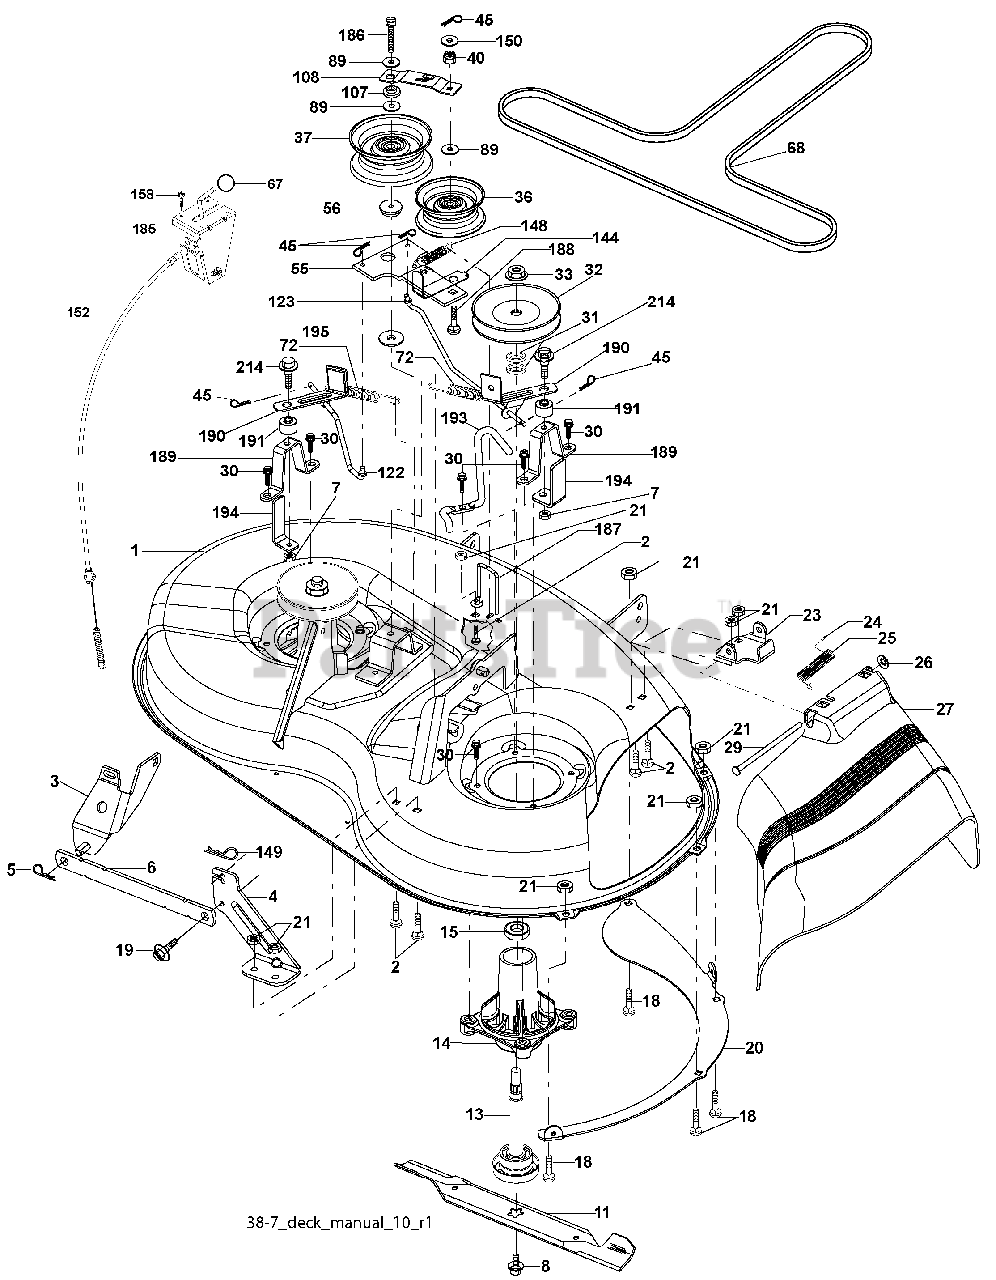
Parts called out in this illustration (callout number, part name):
1	Mower Housing Assembly
2	Bolt Carriage 5/16-18 x 3/4
3	Bracket Asm Fr. Sway Bar
4	Bracket Deck Sway Bar 38"/42"
5	Retainer Spring
6	Bar Sway Deck
7	Nut Lock 5/16-18 unc
8	Bolt 3/8-24 x 1.25 Gr. 8
11	Blade Mower
13	Shaft Assembly, Mandrel, Vented
14	Housing, Mandrel, Vented
15	Bearing, Ball, Mandrel
18	Blade Rdhd Sqnk 5/16-18 x 5/8
19	Bolt, Shoulder
20	Baffle Vortex Front
21	Nut
23	Bracket, Mower Deflector
24	Cap, Sleeve
25	Spring, Torsion, Deflector
26	Nut, Push
27	Shield, Deflector
29	Rod, Hinge
30	Screw Thdrol.
31	Washer, Spacer
32	Pulley, Mandrel
33	Nut, Toplock
36	Pulley, Idler, Flat
37	Pulley, Idler, Flat
40	Nut, Crownlock 3/8-16 unc
45	Retainer
55	Idler Arm Assembly
56	Spacer, Retainer
67	Knob
68	V-Belt
72	Spring Brake Return
89	Washer 13/32 x 13/16 x 11 Ga.
107	Spacer Retainer
108	Stiffener, Idler Arm
122	Rod, Brake LH
123	Rod, Brake RH
144	Keeper Belt Idler Tension
148	Spring Return Idler
149	Retainer Spring Yellow
150	Washer 9/32 x 3/4 x 10 Ga.
152	Clutch Cable 38"
158	Screw Hex Thd Cut 1/4-20 x 1/2
185	Head Asm Cable Clutch
186	Screw Hex Wsh Thdrol 3/8-16 x 2-3/4
187	Keeper Belt M Shape
188	Bolt Carriage Idler
189	Brake Stand
190	Brake Arm
191	Brake Spacer
193	Keeper Belt RH Mandrel
194	Brake Guard
195	Washer 13/32 x 2 x 10 Ga.
196	Brake Assembly
214	Bolt/Washer Asm. 5/16-18
214	Mandrel Assembly
214	Replacement Mower, Complete
